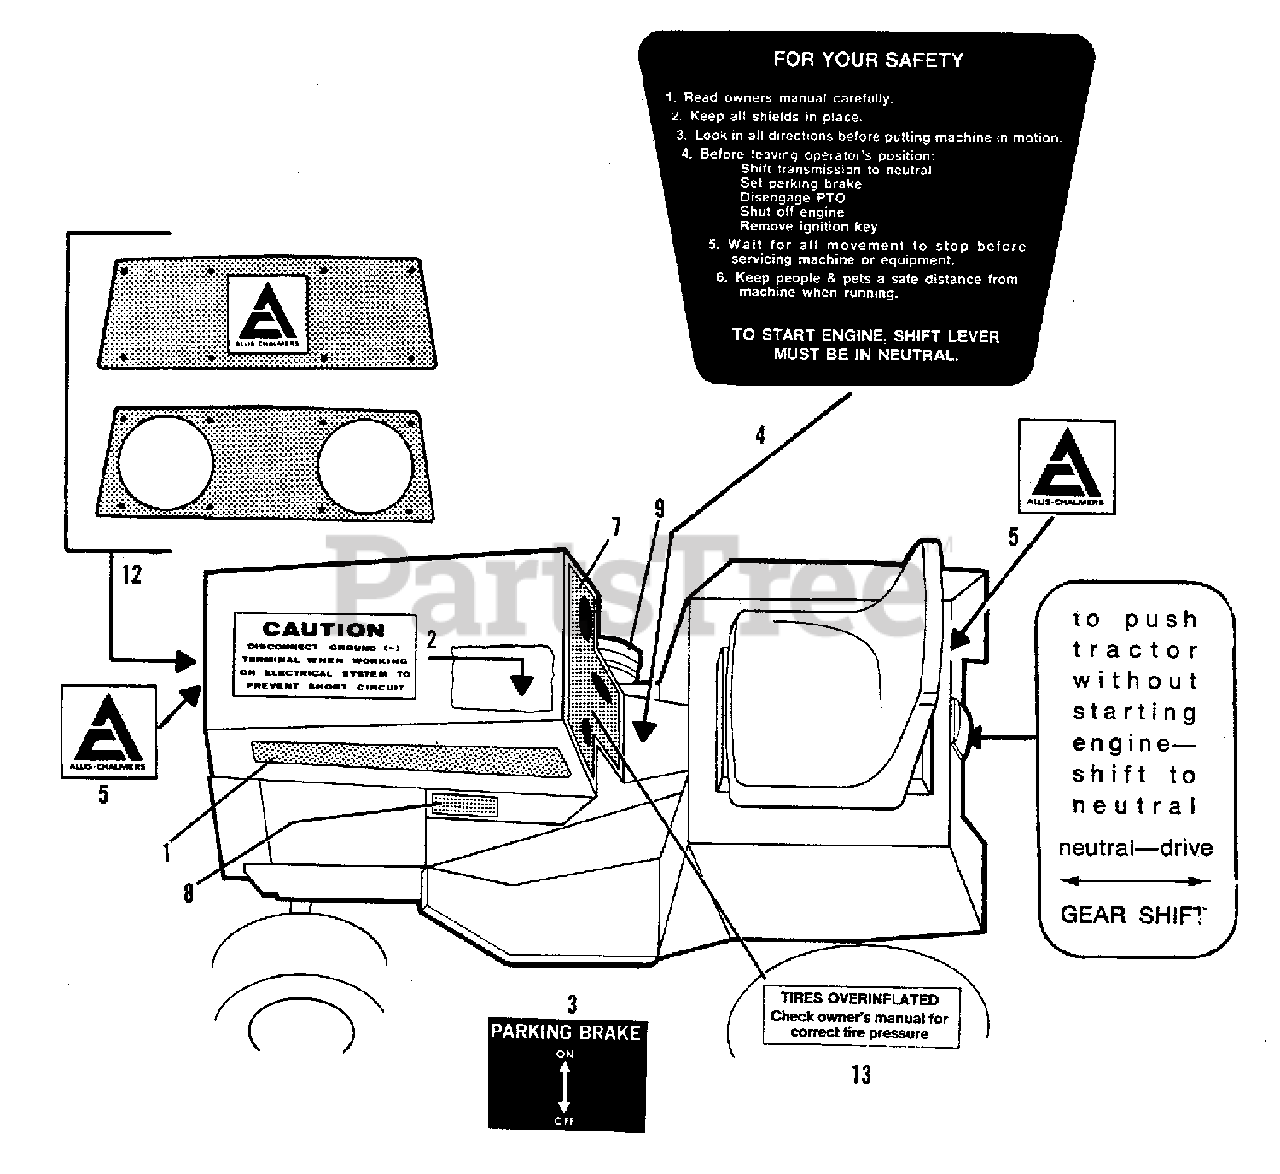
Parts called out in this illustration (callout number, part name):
1	DECAL, L.H. Hood (410 & 410-S)
1	DECAL, R.H. Hood (410 & 410-S)
1	DECAL, L.H. Hood (414-S & 414-H)
1	DECAL, R.H. Hood (414-S & 414-H)
1	DECAL, L.H. Hood (416-S & 416-H)
1	DECAL, R.H. Hood (416-S & 416-H)
2	DECAL, Caution
3	DECAL, Brake
4	DECAL, Safety (410, 410-S, 414-S, 416-S)
4	PLATE, Safety (414-H & 416-H)
5	DECAL, Trademark
6	DECAL, Lift Lever
7	INSERT, Instrument Panel (Standard 410 Only)
7	INSERT, Instrument Panel (Shuttle Clutch Models)
7	INSERT, Instrument Panel (Hydrostatic Models)
8	DECAL, Shuttle (410-S, 414-S, 416-S)
8	DECAL, Hydrostatic (414-H, 416-H)
9	DECAL, Hydrostatic Quadrant
10	DECAL, Shift
11	DECAL, Front P.T.O.
12	DECAL, Headlight Panel
13	DECAL, Wheel & Tire
